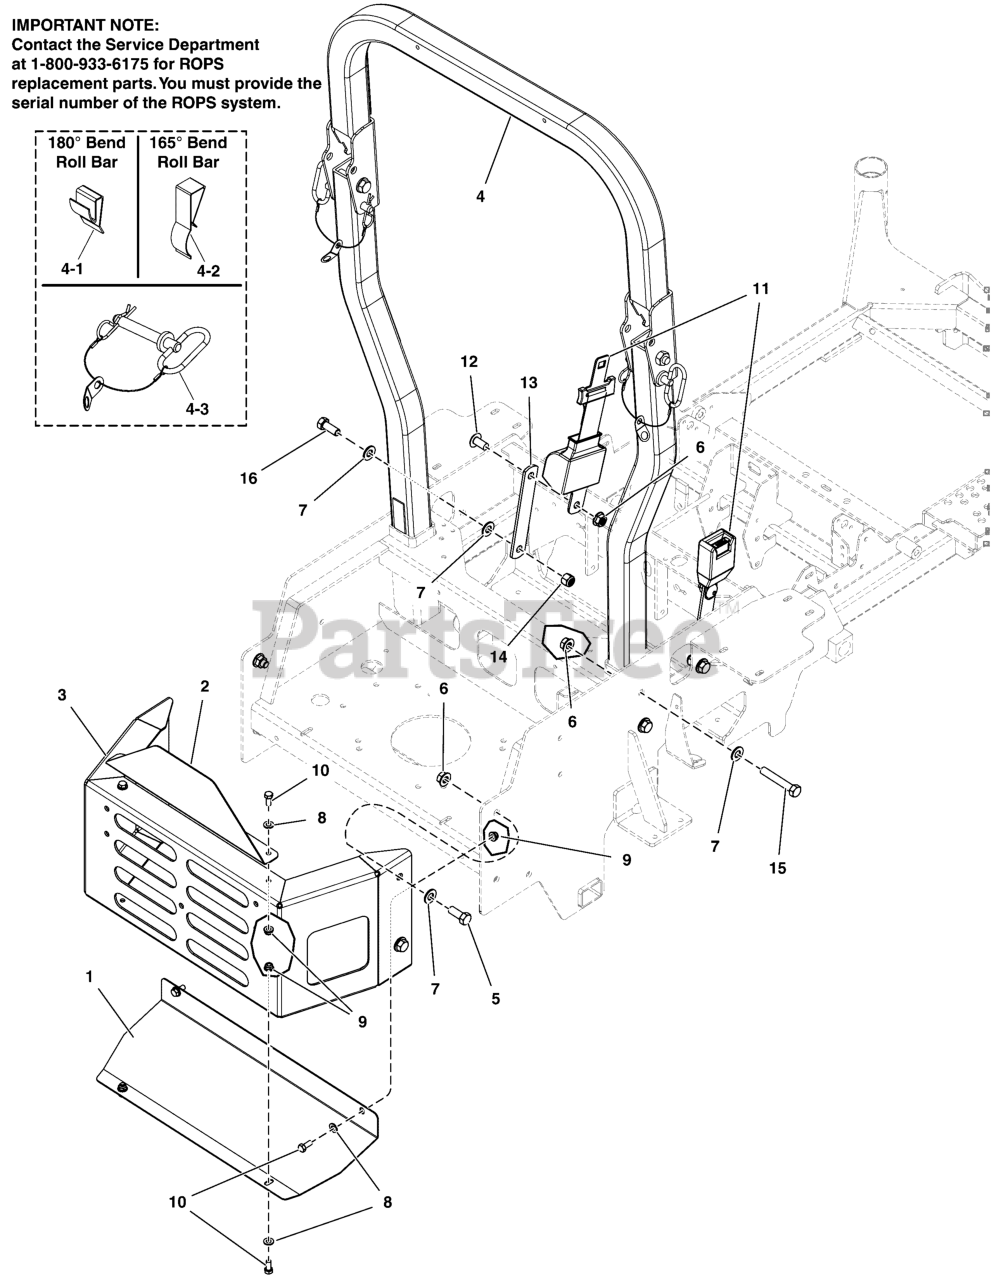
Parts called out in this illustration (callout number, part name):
1	PLATE, HEAT SHIELD, S125XT - BLACK
2	PLATE, CARB PROTECTOR - RED
3	WELD, BUMPER, S125XT - RED
4-1	ANTI-RATTLE SPRING, FEMCO #230328972 (SV)
4-2	ANTI-RATTLE SPRING, ROPS, 165 DEGREE (SV)
4-3	PIN, HITCH, .50 X 3.25 W/ LAY (SV)
5	BOLT, 1/2-13 X 1-1/4 GD5 CZ
6	NUT, Hex Flange, Nylock, 1/2-13
7	WASHER, 1/2 SAE
8	WASHER, 5/16" SAE
9	NUT, 5/16-18 HEX NYLOCK FLANGE NUT
10	BOLT, 5/16-18 X 3/4 GD5
11	SEAT BELT, RETRACTING - ASSM - RED
12	SCREW, 1/2 - 13 X 1.00 SCHS
13	BAR, MOUNT, SEAT BELT, IS700Z - BLK
14	NUT, 1/2-13 HEX NYLON LOCK
15	BOLT, 1/2-13 X 3" GD5 CZ
16	BOLT, 1/2-13 X 1-1/2 GD5 CZ
